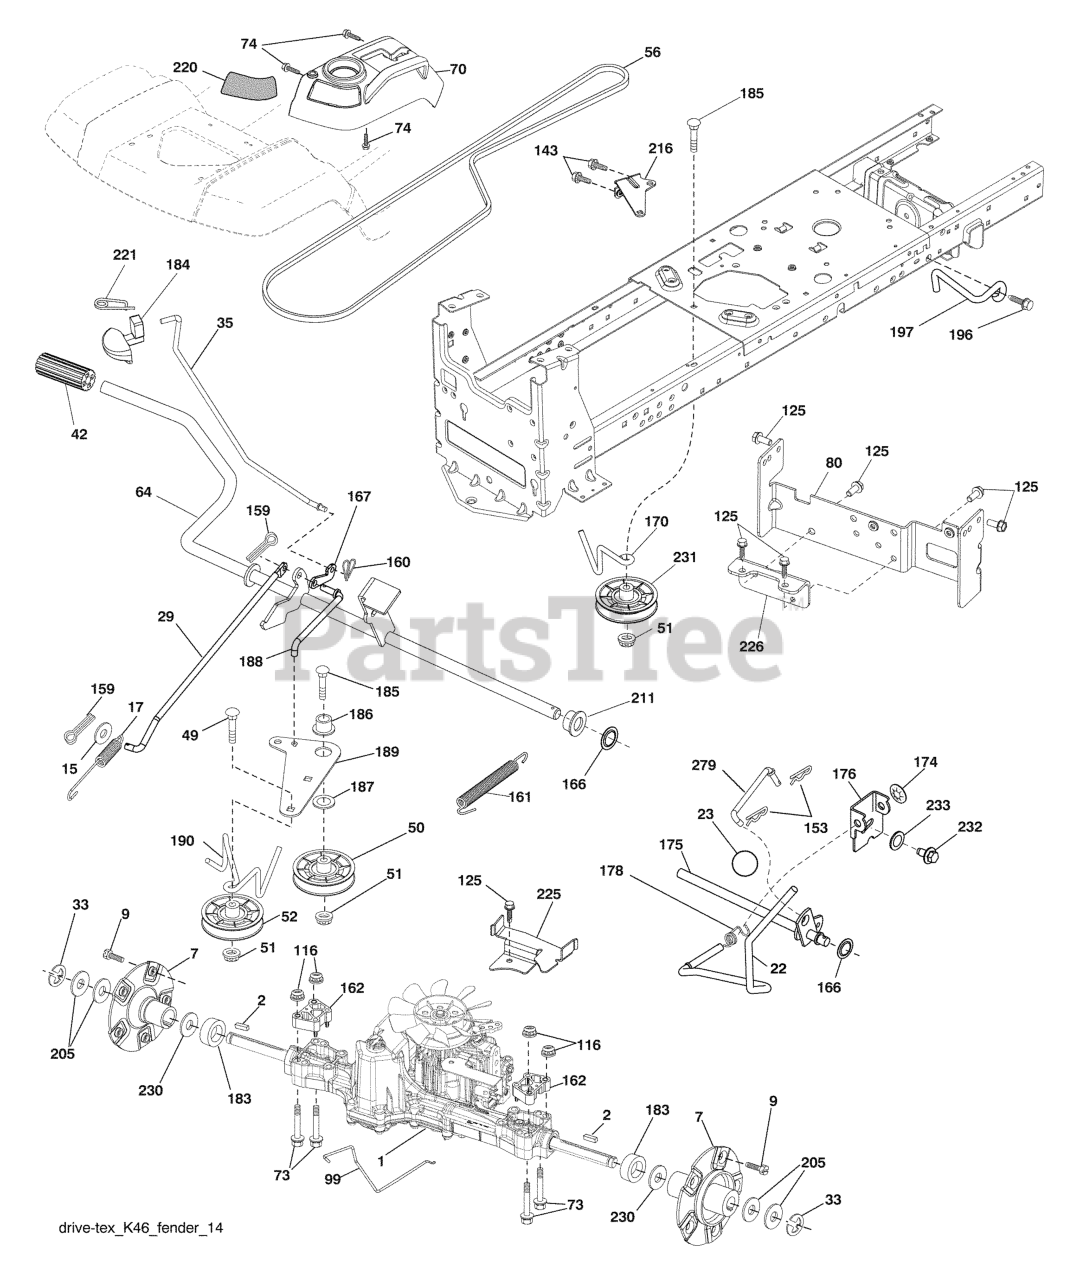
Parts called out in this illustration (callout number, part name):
1	TRANSAXLE(K46AW)22"FS
2	KEY.SQUARE.187X2.500
7	HUB.ASM.WHEEL.REAR.22"
9	HUB BOLT
15	WASHER
17	SPRING.BRAKE.K46.GREEN
22	ROD.SHIFT.FENDER.STGT.
23	KNOB.DELUXE.(PISTOL.GRIP).BLAC
29	ROD.BRAKE.K46
35	ROD.BRAKE.PARKING.GT.H
42	PEDAL COVER T
49	BOLT
50	IDLER.FLAT.910.OFFSET
51	NUT LOCK FLG 3/8-16 UNC
52	IDLER.V-GROOVE.910.OFFSET
56	V-BELT.MOWER.92.40.42/K46
64	SHAFT.ASM.PEDAL.BRAKE.
70	RP CONSOLE.ASM.HYDO.HUSQ.
73	BOLT.HEX.FLNG.5/16-18X3.75
74	SCREW.HI-LO.CONSOLE
80	STRAP TORQUE
99	ROD.SPRING.BYPASS.K46.TEX.GT
116	NUT LOCK HEX FLANGE 5/16-18
125	SCREW
143	Screw 5/16-18 x 1/2
153	RETAINER M
159	COTTER PIN
160	RETAINER CLIP
161	SPRING, RETURN LT
162	SPACER.TRANSAXLE.18&22
166	NUT.PUSH.625
167	LATCH.BRAKE.SPRING
170	KEEPER.CENTER SPAN.1.688
174	NUT.PUSH.500.2006
175	SHAFT ASM SHIFT
176	ARM.CLEVIS.ROD.SHIFT
178	SPRING.SHIFT.GT2006
183	SPACER.SPLIT.800X.350
184	HANDLE.PARKG.BRK.HUSQ X667
186	SPACER.RETAINER
187	WASHER 12/32X2X10GA
188	RP.LINK.CLUTCH.GROUND.DRIVE
189	BELLCRANK.GROUND.DRIVE.TEX.
190	KEEPER.BELLCRANK.DRIVE
196	SCREW 3/8-16X1
197	BRKT.ANIT-ROTATION.CLUTCH
211	BUSHING.SHAFT.BRAKE.HAND
216	BRACKET.PULLEY.IDLER.W/TEX
220	REFLECTOR.RH.TEX GT
221	RETAINER.SPRING.CLIP.H
225	KEEPER.BELT.TRANSAXLE.K46
226	BRKT.MOUNT.TORQUE.K46.
230	WASHER.HARDENED
231	IDLER.V-GROOVE.1.688.OFFSET
232	BOLT FIN HEX 7/16-14 X 1
233	WASHER SERRATED
279	LINK.SHIFT.T/A.K46.FEND.TX
